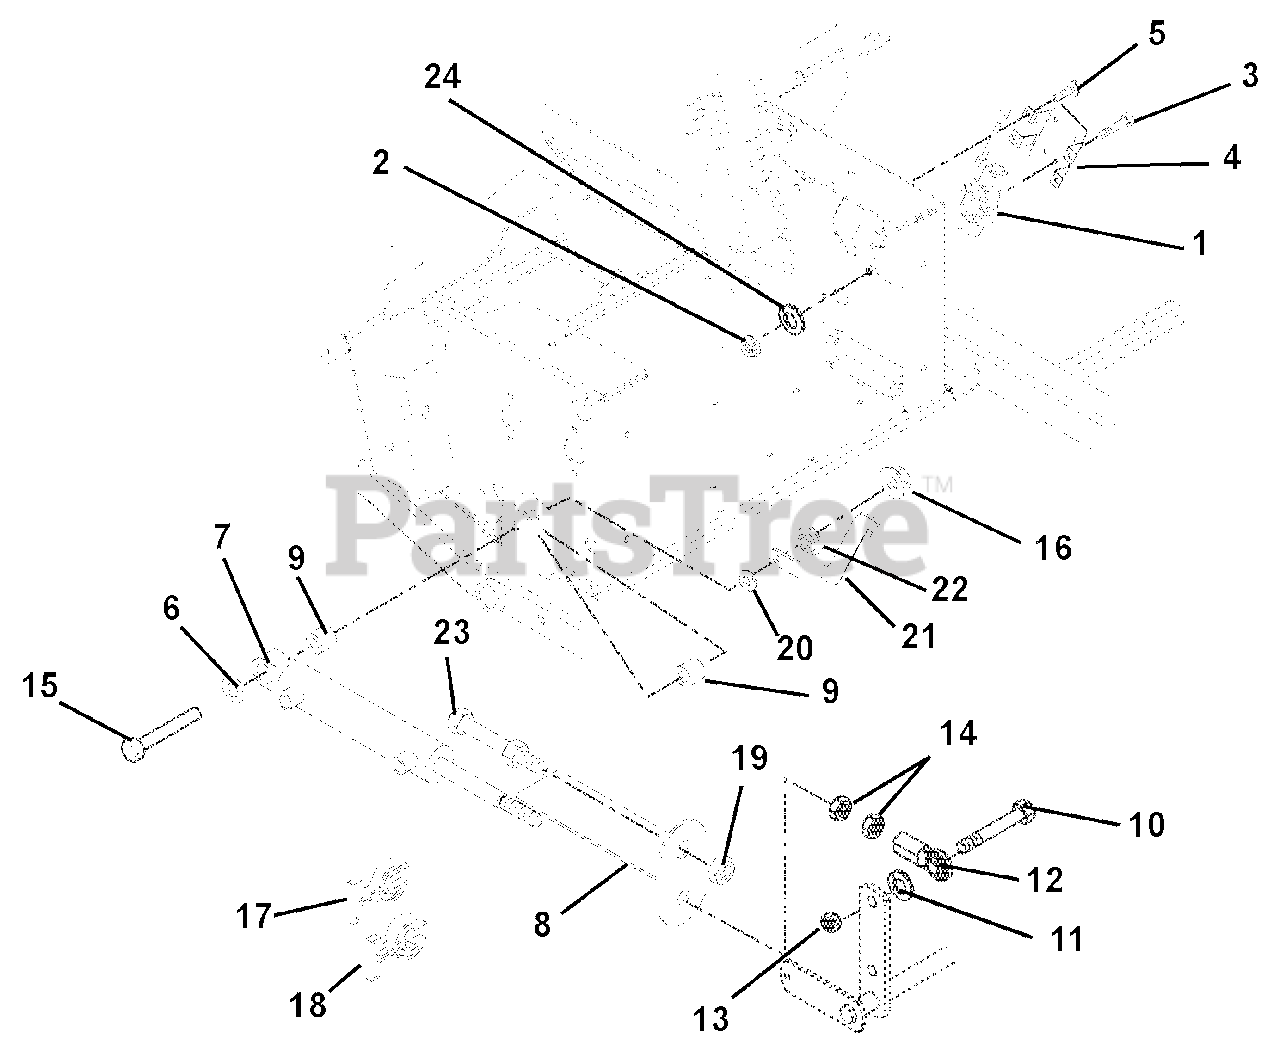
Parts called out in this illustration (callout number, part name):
1	VALVE - HYDRAULIC LIFT
2	@NUT-LK-CTR .31-18 YWZC
3	@BLT-HEX .31-18X2.00 GR5 YWZC
4	BRACKET - VALVE MOUNTING
5	@SCR-TAP .38-16X.50 HWH TR YWZ
6	WSHR-FL-STL .515X1.625X.250 YZ
7	CYLINDER, LIFT
8	CUT INDICATOR/GUARD - BLACK
9	BUSHING, .516X1.000X1.050 LG
10	BLT-HEX .62-11X2.25 YWZC GR8
11	@WSHR-LK .62X.156 REG YWZC
12	ROD END, 5/8 RH - FEMALE
13	@NUT-LK-CTR .62-11 YWZC
14	NUT-JAM .625-18 YWZC
15	@BLT-HEX .50-13X3.75 GR5 YWZC
16	@NUT-LK-TOP-FLG .50-13 YWZC
17	STOP, CYLINDER .34 THK
18	STOP, CYLINDER .680 THK
19	NUT-JAM .75-16 YWZC
20	WASHER-WAVE .760X1.120X.080
21	LATCH, FOOTBOARD HOOK
22	BSHG-FLG .515X.750X.285X1.120
23	ASM,FSTNR 30" ROTARY MWR
24	@WSHR-LK .31X.078 REG YWZC
